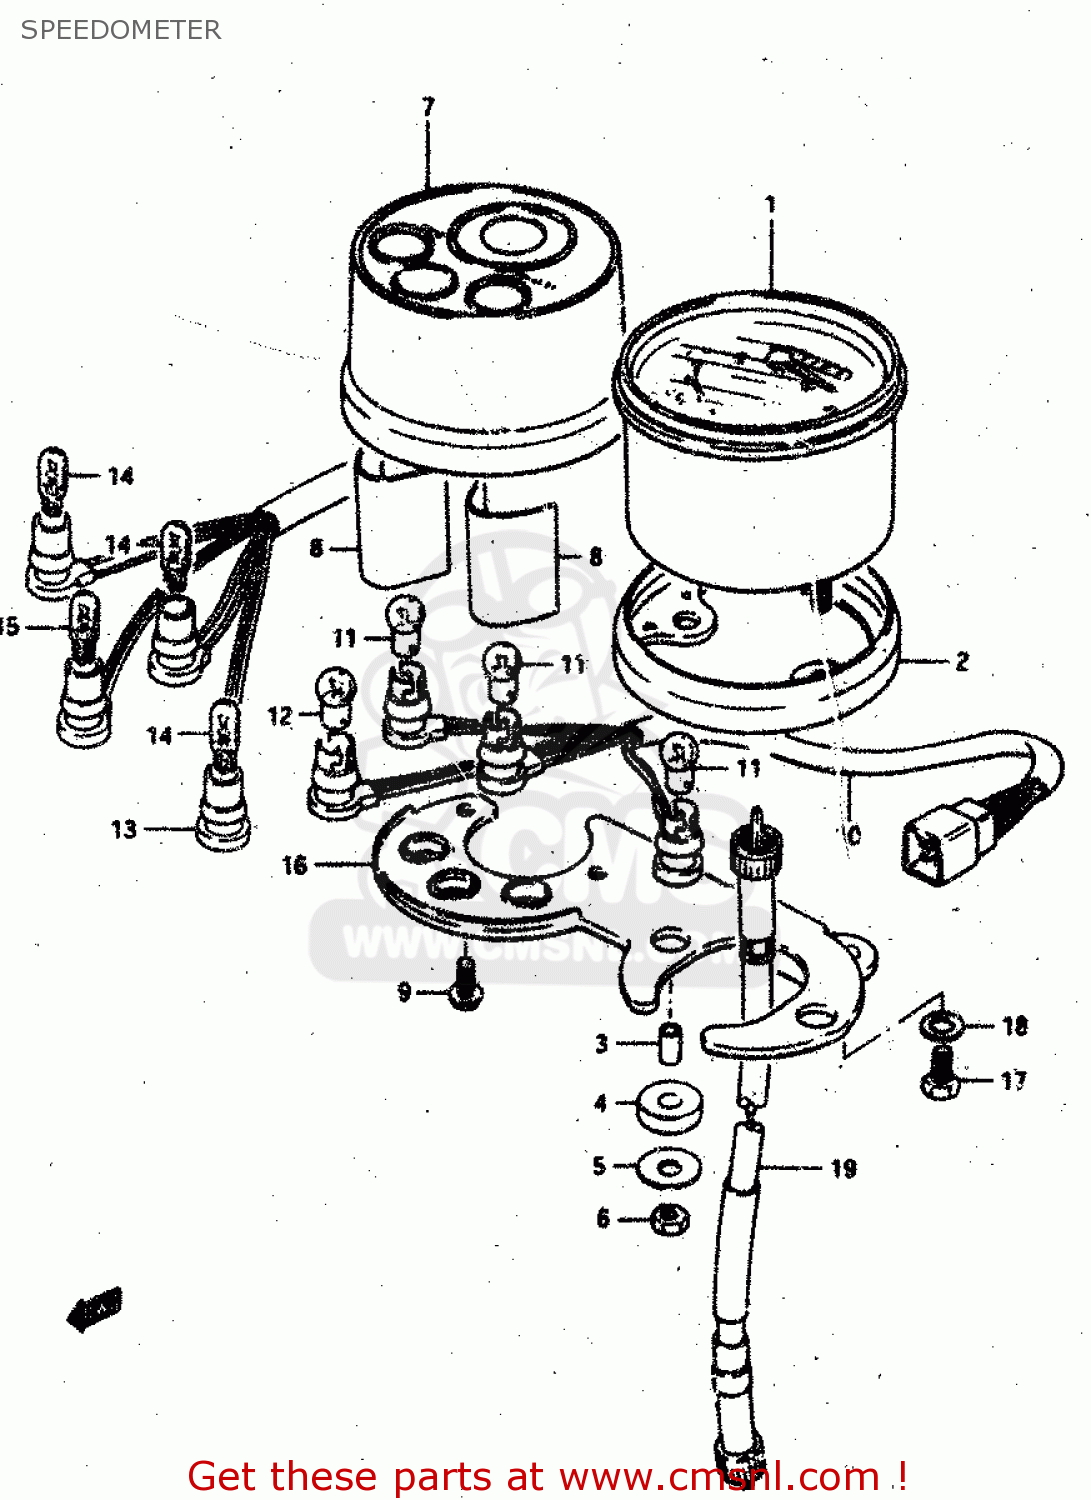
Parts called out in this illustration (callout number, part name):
1	SPEEDOMETER
2	CUSHION
3	SPACER
4	CUSHION,SPEEDOMETER
5	WASHER (5.5X24X1.6)
6	NUT
7	CASE
8	REFLECTOR,PILOT LAMP
9	BOLT
10	SOCKET
11	BULB(6V/3W)
12	BULB(6V1.7W,STANLEY,A61A)
13	SOCKET
14	BULB(6V,3W)
15	BULB(6V1.7W,STANLEY,A61A)
16	BRACKET,SPEEDOMETER
17	BOLT 8X12
18	WASHER
19	CABLE ASSEMBLY,SPEEDOMETER
